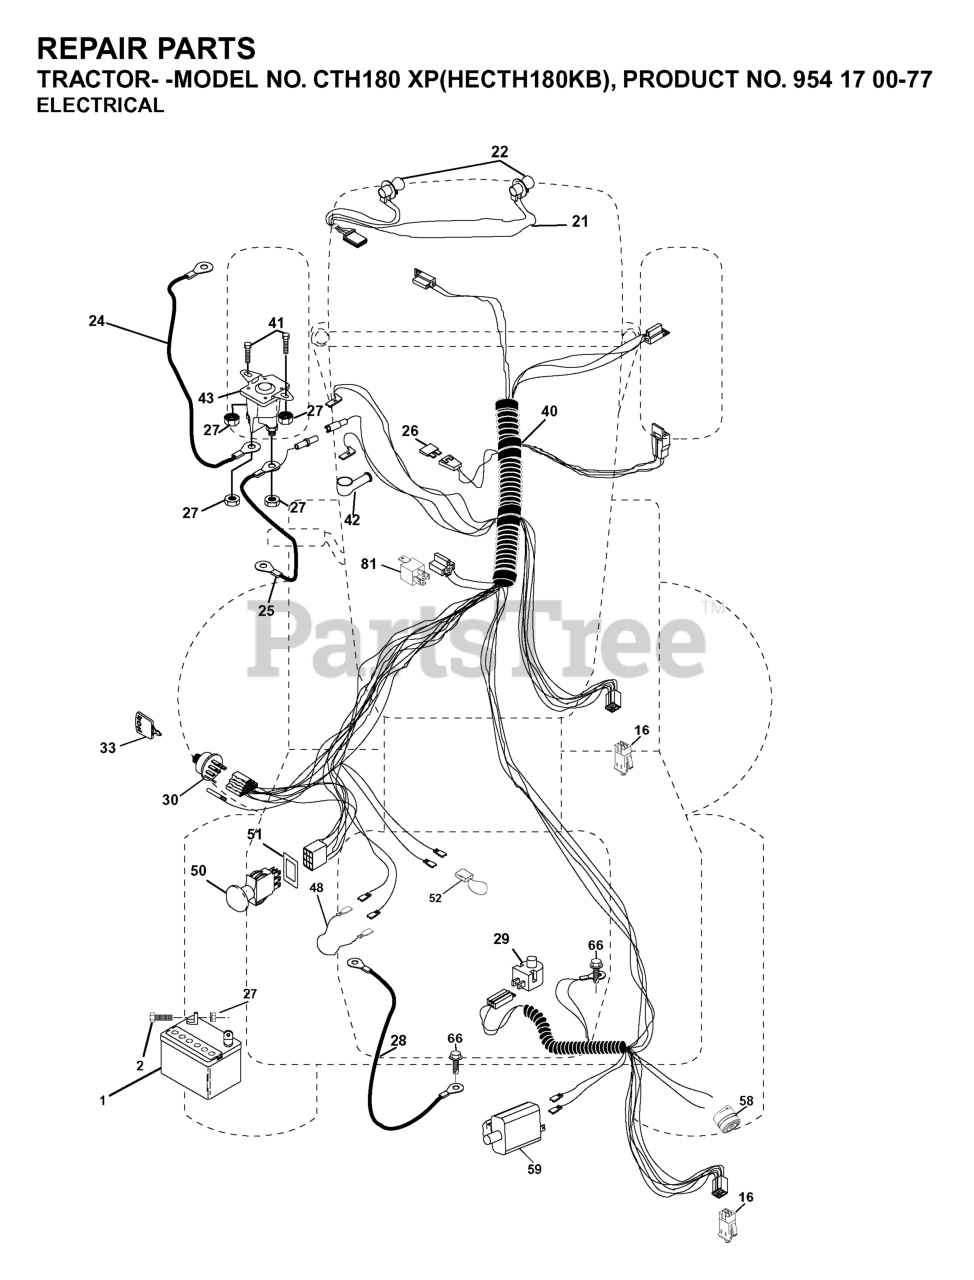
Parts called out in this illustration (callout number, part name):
1	BATTERY 12V .35 AMP
2	BOLT.HEX.1/4.X.3/4.DICHROMATE
16	SWITCH INTERLOOK PUSH-IN
21	HARNESS.W/LIGHT SOCKET
24	BATTERY CABLE GT
25	CABLE BATTERY
26	FUSE 20AMP
27	NUT
28	CABLE GROUND
29	PLUNGER SWITCH (COLOR:OLIVE)
30	IGNITION SWITCH
33	KEY MLD GEN DELTA
41	BOLT
42	TERMINAL COVER
43	SOLENOID
48	ADAPTER.AMMETER
50	RP.PTO.SWITCH.8 TERMINAL.BLACK
51	FRAME RETAINING RING
52	WIRE PROTECTION LOOP
58	BUZZER
59	.WITCH.FULL BAGGER.INDICATOR
81	RELAY.ASSY.T
